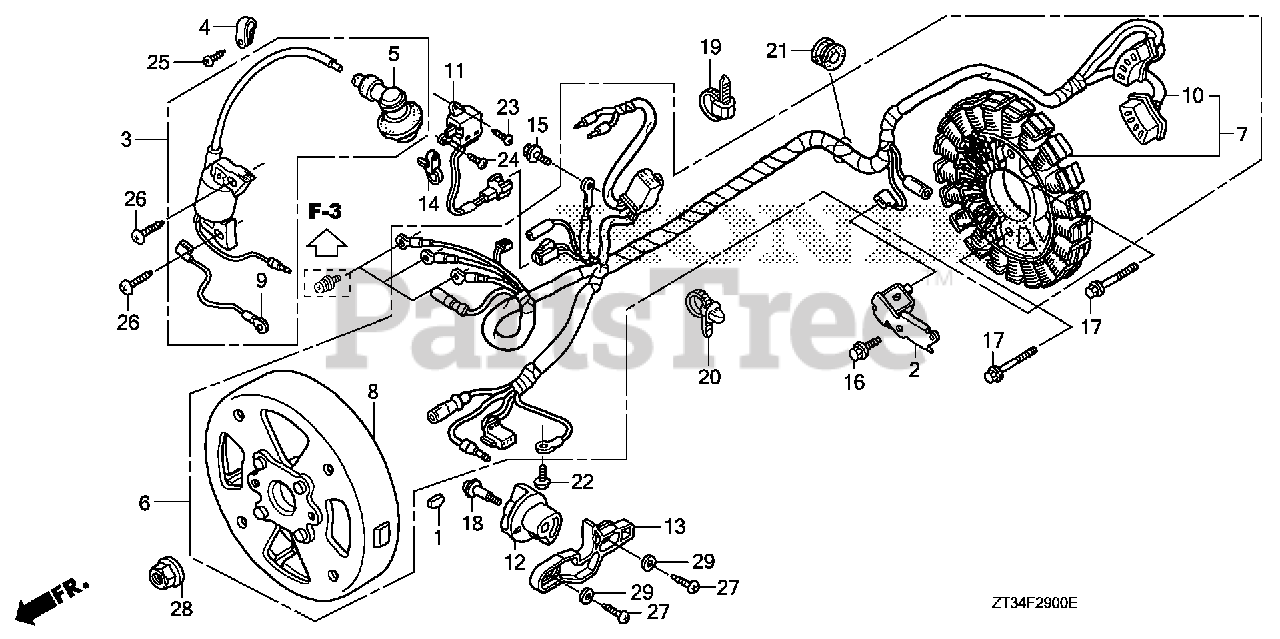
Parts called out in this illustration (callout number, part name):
1	KEY, SPECIAL
2	COIL, PULSER
3	COIL ASSY., IGNITION
4	CLAMP A, CABLE
5	CAP ASSY., NOISE SUPPRESSOR
6	GENERATOR ASSY.
7	STATOR ASSY.
8	ROTOR
9	WIRE, IGNITION GROUND
10	WIRE HARNESS ASSY., GENERATOR
11	SWITCH ASSY., ENGINE STOP
12	KNOB, ENGINE SWITCH
13	PLATE, ENGINE SWITCH
14	BAND, HARNESS
15	BOLT, FLANGE (5X8)
16	BOLT, FLANGE (5X12)
17	BOLT, FLANGE (5X25) (CT200)
18	SCREW, PAN (4X19)
19	BAND, WIRE (95MM)
20	STRAP, CABLE (118MM) (BLACK)
21	GROMMET, GENERATOR CORD
22	SCREW, PAN (5X8)
23	SCREW, TAPPING (3X10)
24	SCREW, TAPPING (3X16)
25	SCREW, TAPPING (5X12)
26	SCREW, TAPPING (6X20)
27	SCREW, TAPPING (5X20) (PO)
28	NUT, FLANGE (10MM)
29	WASHER, PLAIN (5MM)
